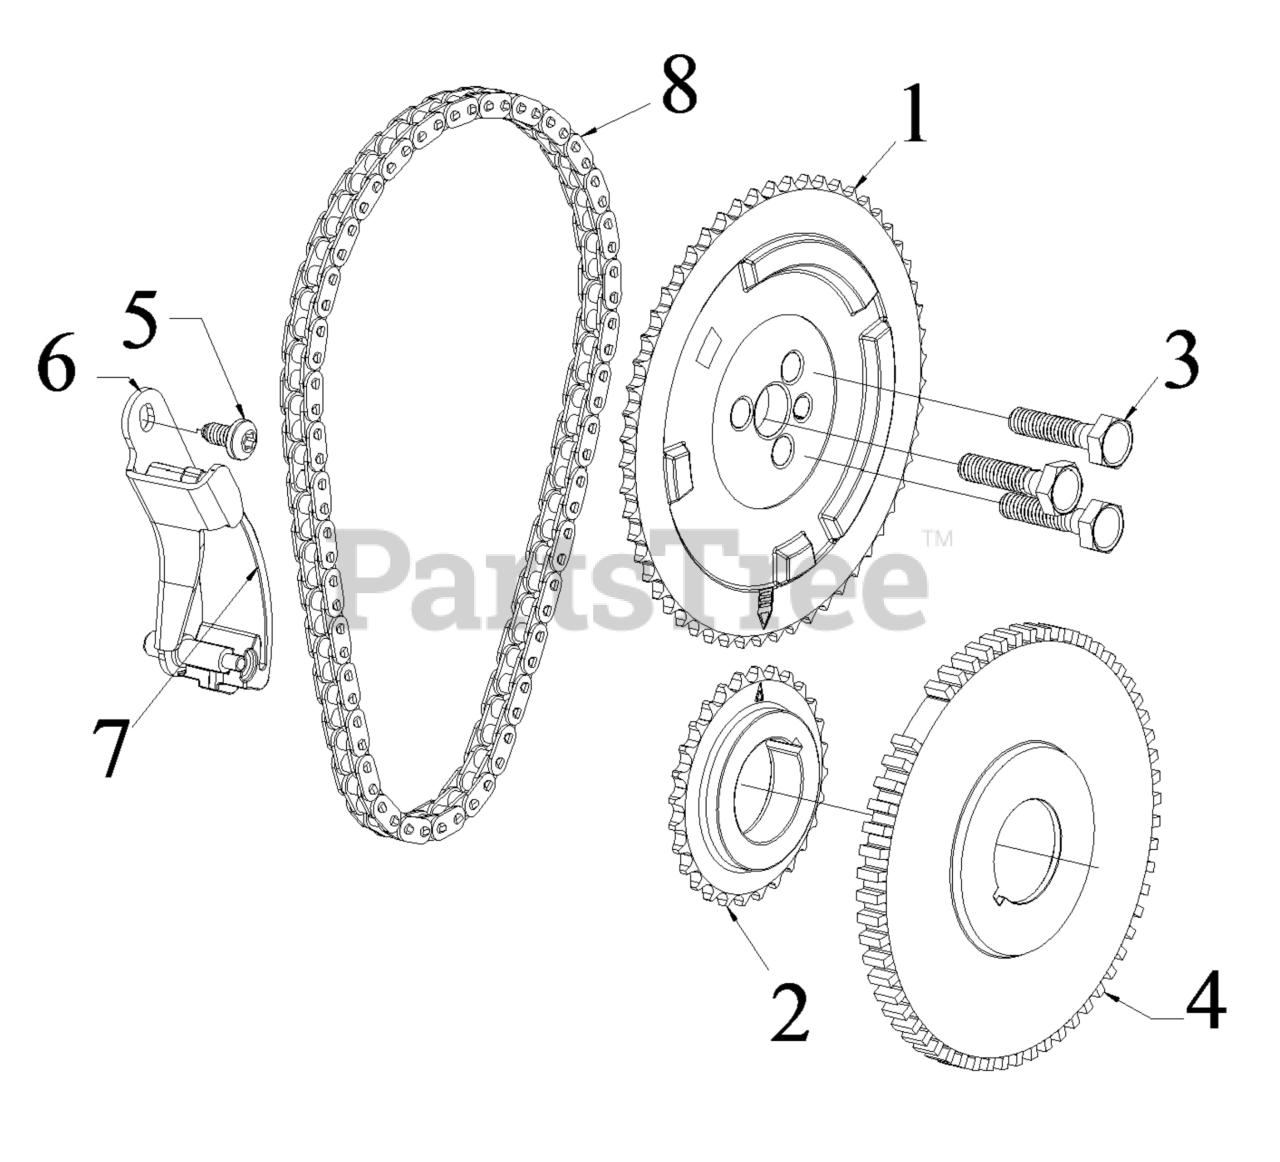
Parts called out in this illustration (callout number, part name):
1	*KIT, TIMING CHAIN AND SPROCKETS
2	*KIT, TIMING CHAIN AND SPROCKETS
3	*BOLT, CAMSHAFT SPROCKET
4	*RING, CRANKSHAFT POSITIONER
5	*BOLT, BALANCER SHAFT RETAINER
6	*GUIDE, TIMING CHAIN
7	*GUIDE, TIMING CHAIN
8	*KIT, TIMING CHAIN AND SPROCKETS
